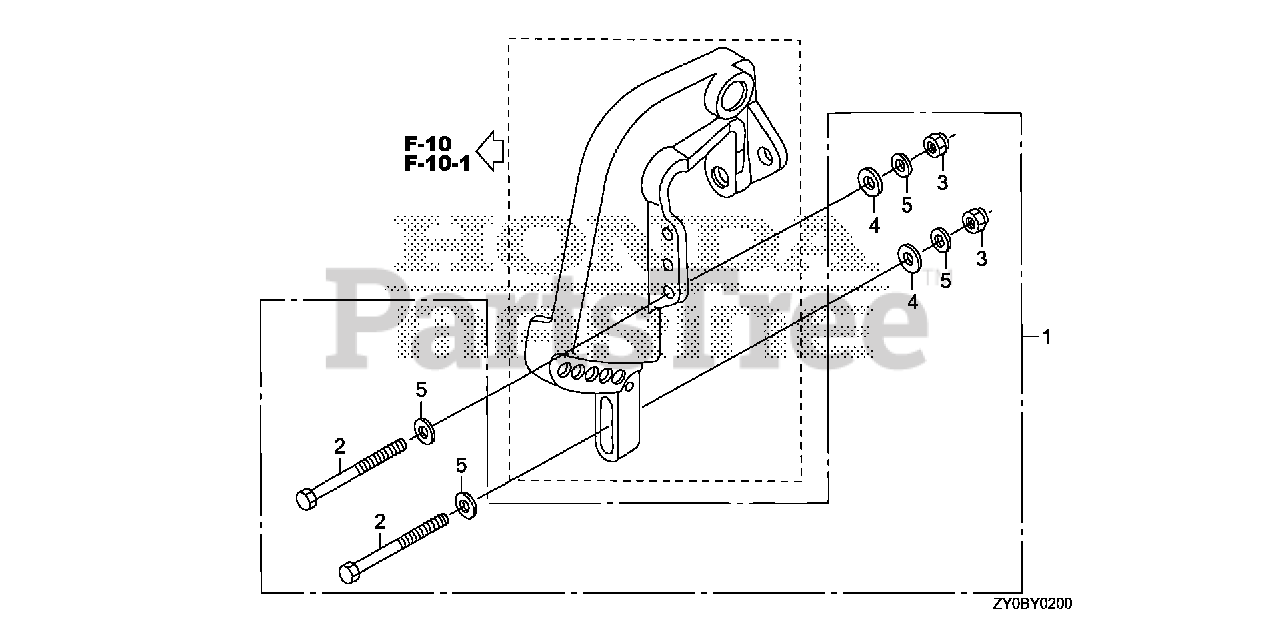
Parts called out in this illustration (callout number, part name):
1	INSTALLATION KIT, OUTBOARD
2	BOLT, HEX. (10X100)
3	NUT, SELF-LOCK (10MM)
4	WASHER, PLAIN (10MM)
5	WASHER, PLAIN (10MM)
